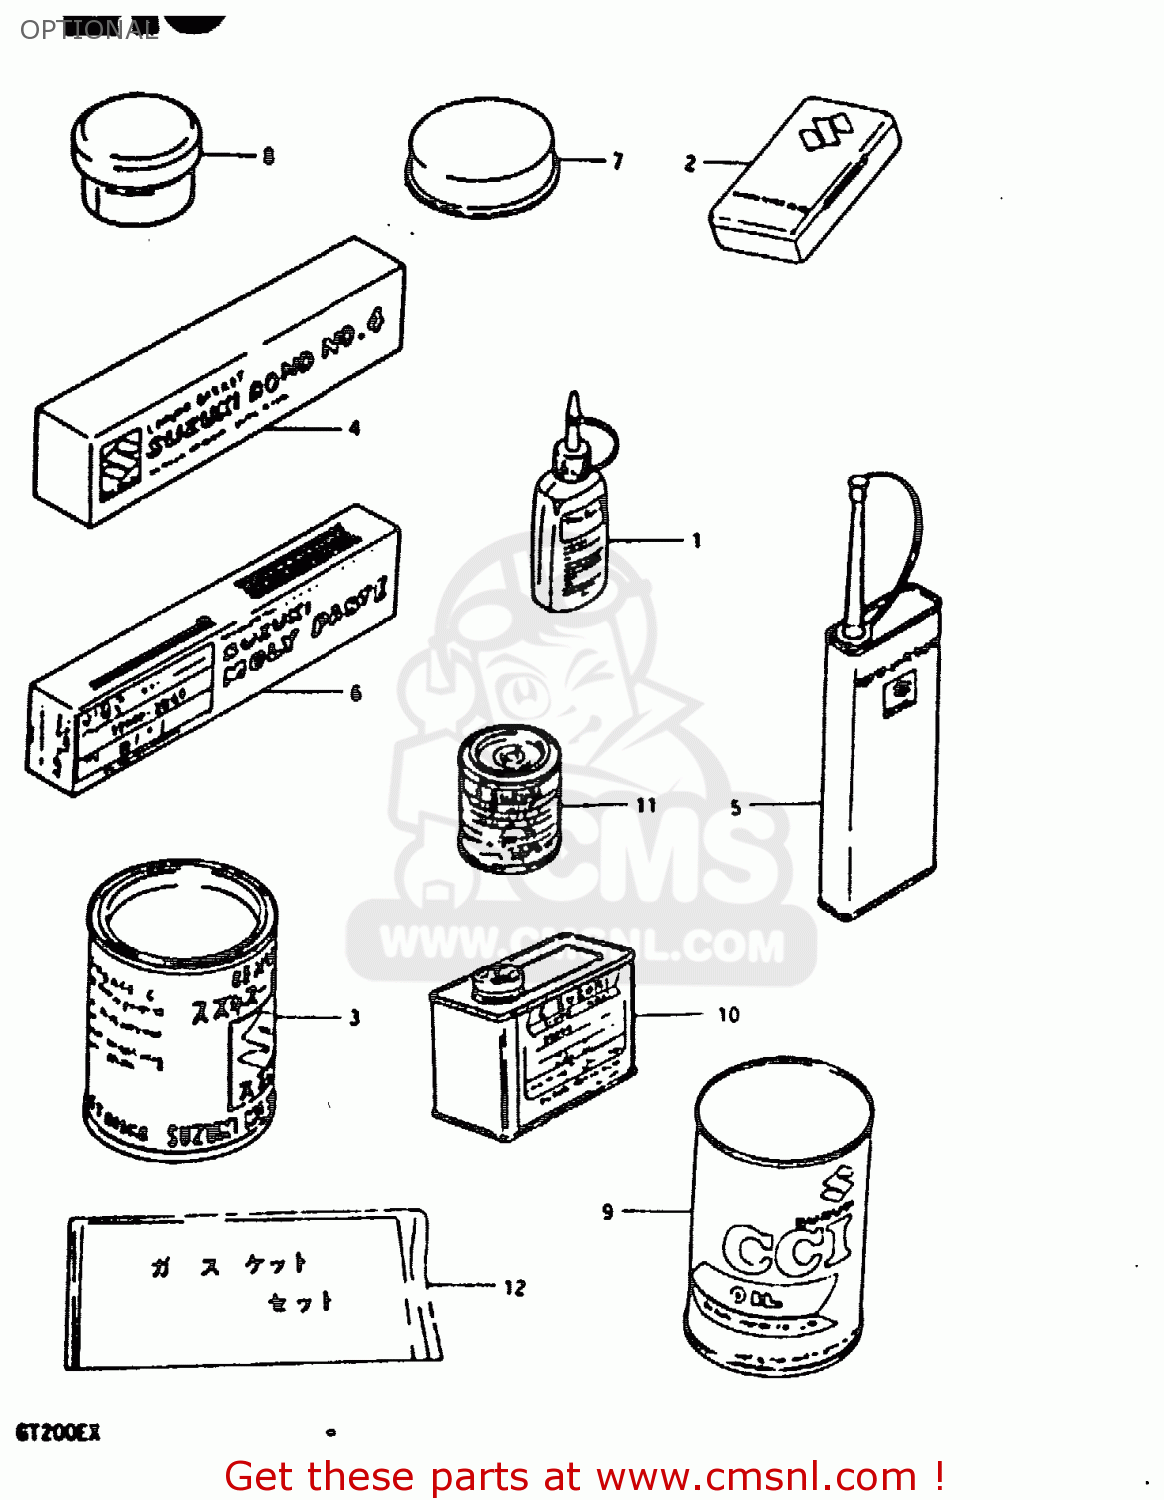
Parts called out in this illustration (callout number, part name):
1	THREAD LOCK NO.1303B PURPL 50G
2	TUBE REPARING TOOL
3	GREASE(C)EP2 LITHIUM 150G
4	BOND 1104
5	THREAD LOCK NO.1401 CLEAR 200G
6	SUZUKI MOLY PASTE
7	GREASE,SILICON 20G
8	GREASE,PBC FOR BRK PAD 20G
9	CCI OIL
10	PAINT (BLACK)
11	PAINT,BLACK
12	GASKET SET
